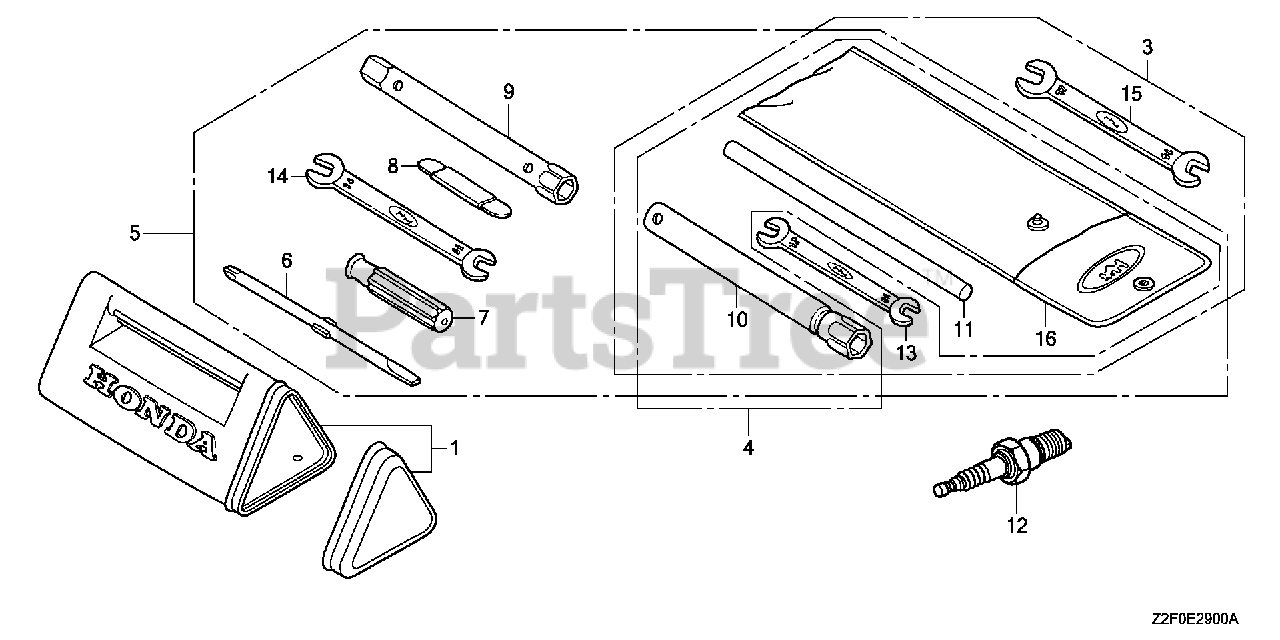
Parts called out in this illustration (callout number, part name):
3	TOOL KIT
10	WRENCH, SPARK PLUG
11	HANDLE, BOX WRENCH
13	SPANNER (10X12)
15	SPANNER (14X17)
16	BAG, TOOL (230MM)
